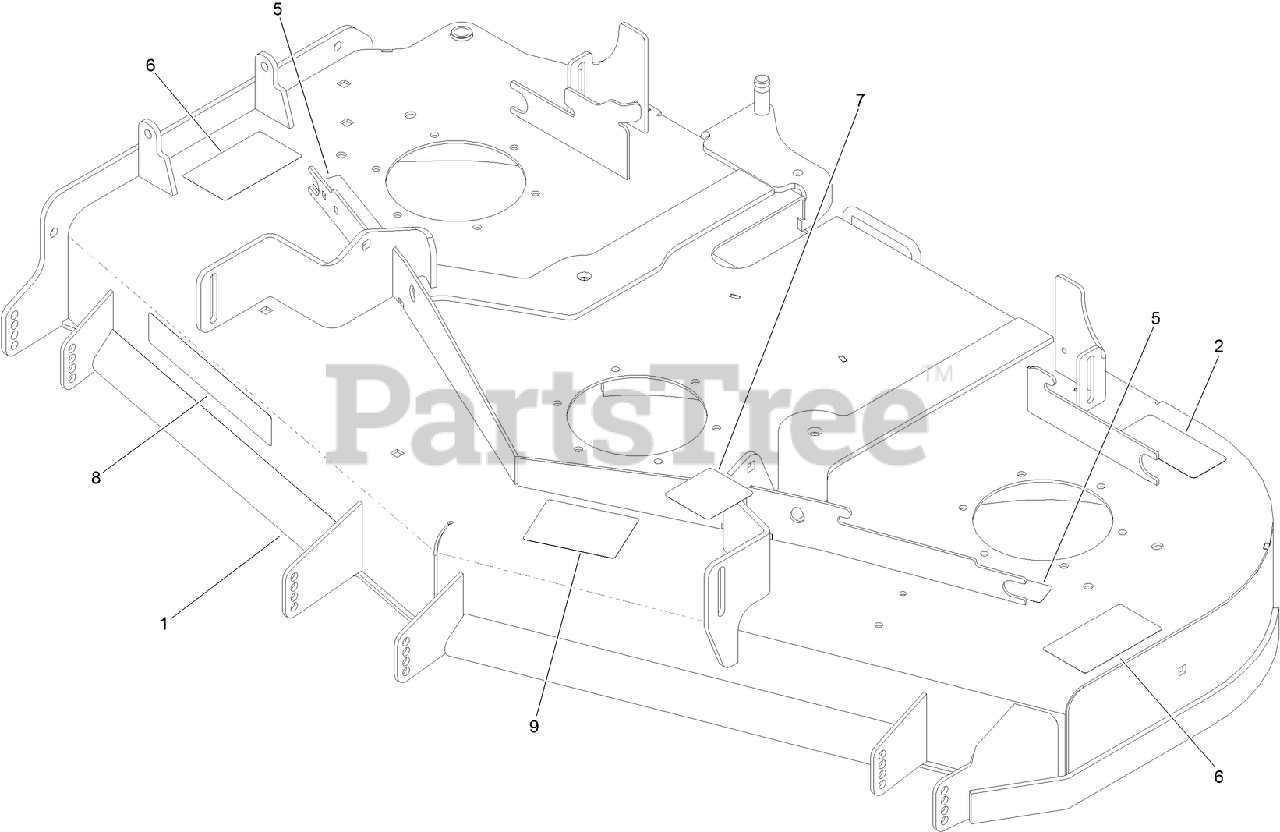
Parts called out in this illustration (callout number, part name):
1	DECK DECAL ASM
2	DECAL-TORQUE, BLADE BOLT
5	DECAL-COVER, MISSING
6	DECAL-DANGER
7	DECAL-ROUTING, BELT
9	DECAL-SCALP, ANTI
